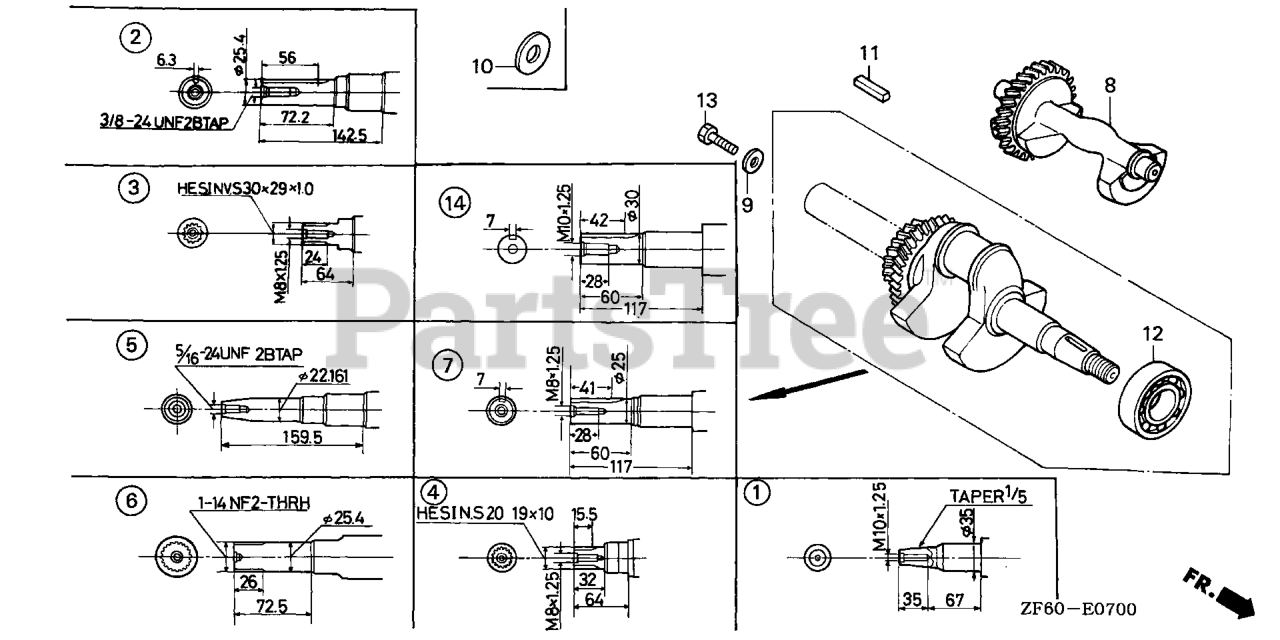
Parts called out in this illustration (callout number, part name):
2	CRANKSHAFT
8	WEIGHT, BALANCER
11	KEY (6.3X6.3X43)
12	BEARING, RADIAL BALL (6207SH)
